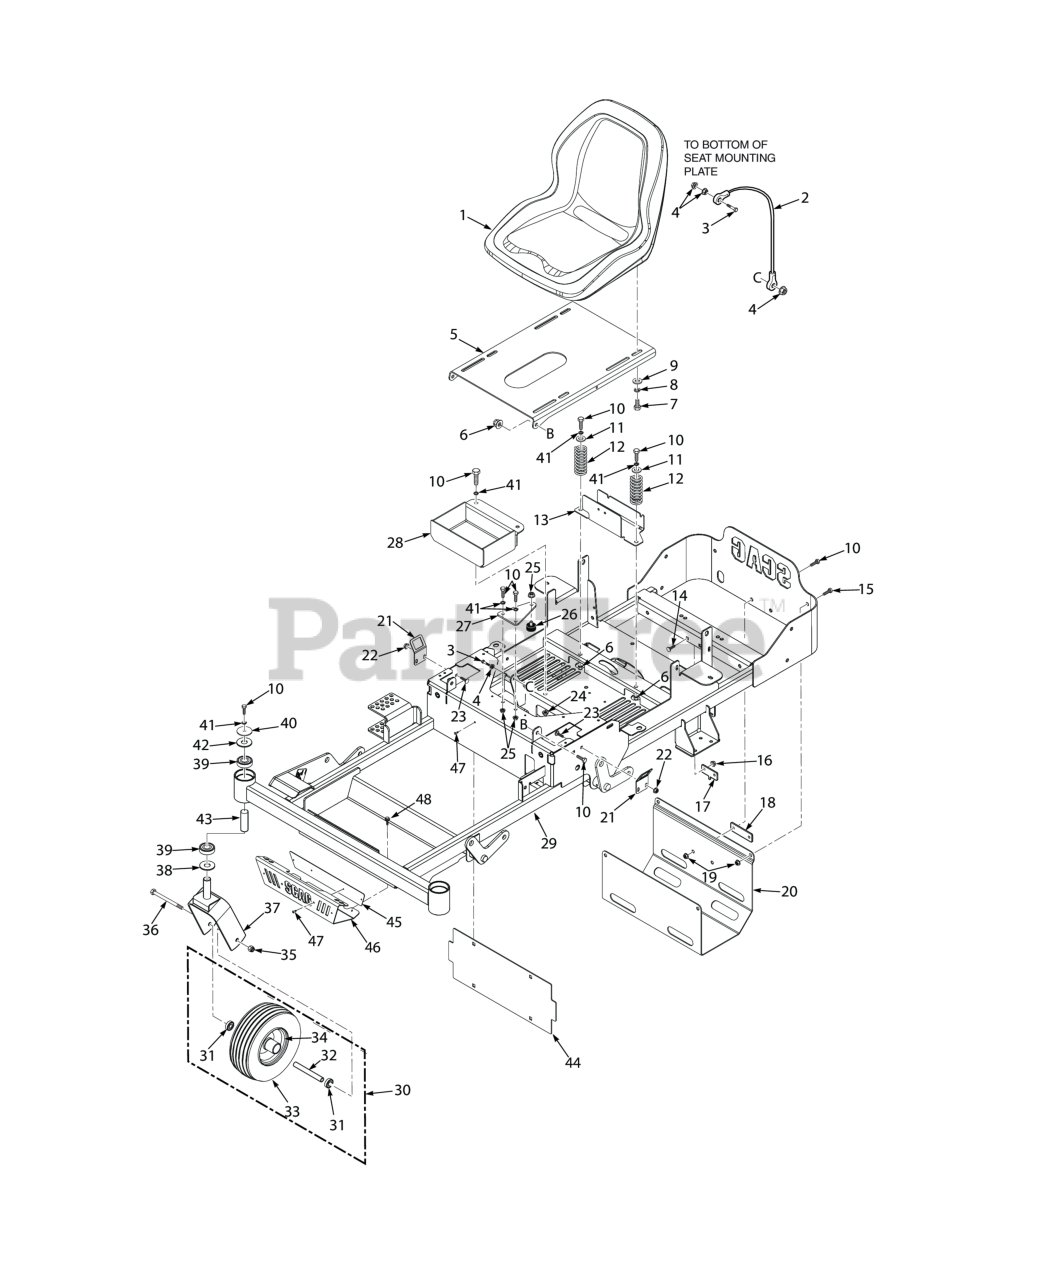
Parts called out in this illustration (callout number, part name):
1	Seat, SZL
2	Cable, Seat Stop
3	SERR. FLG. HEX HEAD CAPSCREW, 5/16-18 X 3/4
4	NUT, 1/4-20 SERRATED FLANGE HEX HEAD
5	Seat-Plate W/Decal
6	Nut, Flange Elastic Stop Nut, 3/8-16
7	Bolt, Heax Head 5/16-18 x 1" (48V / 52V)
8	Lockwasher, 5/16 (.317 x .586 x .078) Helical Spring
9	Flatwasher, 5/16-.375 x .875 x .083 (35BV & 37BV-EFI)
10	Bolt, Hex Head, 3/8-16 x 1 Gr. 5
11	Flatwasher, 3/8" Special (.391 x .938 x .105)
12	Spring, Seat
13	Seat Stop
14	Bolt, 5/16-18 x .75 RHSN Carriage
15	Bolt, Hex Head, 3/8-16 x 3/4"
16	Nut, Flange Head Elastic Stop 5/16-18
17	Plate, Anti-Rotation
18	Plate, Spacer
19	NUT, 3/8-16 SERRATED FLANGE HEX HEAD
20	Skid Plate, SZL-36
21	Bracket, Switch
22	Nut, Flanged Elastic Stop 1/4-20
23	Serr. Fl. Hex Head CPSCR, 1/4-20 x 3/4"
24	Threaded insert, Hex Head (Pressed)
25	Threaded insert, Hex Head (Pressed)
26	Bumper, Rubber 5/16-18 x 5/8"
27	Battery Hold Down
28	Battery Box
29	Frame Assembly, SZL-36H & SZL42H
30	Caster Wheel Assembly
31	Bearing
32	Spacer, Wheel Bearings
33	Tire, 11 x 4-5.00 2-Ply
34	Rim Assembly
35	HEX LOCKNUT, ELASTIC STOP, 1/2-13
36	Bolt, Hex Head 1/2-13 x 6-1/2" (52V)
37	Caster Assembly
38	Spacer, Yoke
39	Bearing
40	Flatwasher, 3/8-.406 x 2.25" x .1875
41	Lockwasher, 3/8" Spring, Kawasaki FX / FS
42	Flatwasher, 7/16" (.500 x 1.25 x .083")
43	Spacer, Caster Bearing
44	Plate, Backing
45	Plate, Decal
46	Bumper. Front
47	Rivot, 3/16 x .402 POP
48	Screw, 1/4-20 x .375"
